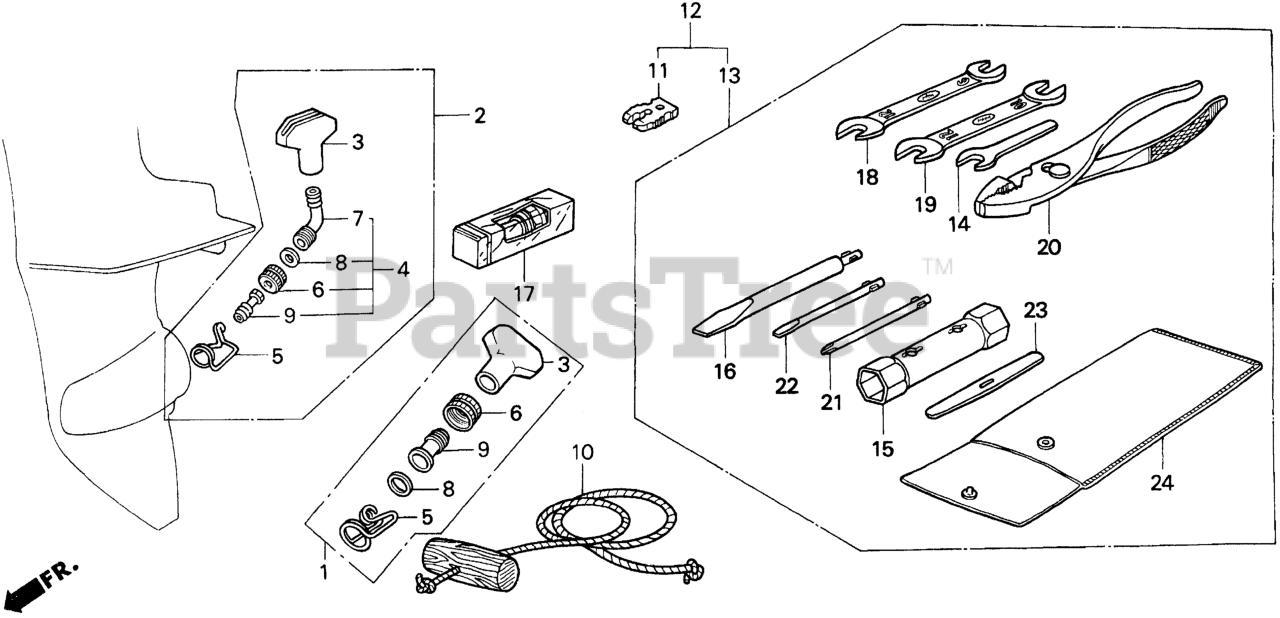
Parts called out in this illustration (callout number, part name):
2	WATER MOUTH KIT Use from Frame SN 1000929 to 1001221.
3	MOUTH, WATER Use from Frame SN 1000929.
5	CLIP, WATER MOUTH Use from Frame SN 1000929.
6	NUT, WATER MOUTH Use from Frame SN 1000929.
7	JOINT, WATER MOUTH Use from Frame SN 1000929 to 1001221.
8	SEAT, WATER MOUTH Use from Frame SN 1000929.
9	JOINT, HOSE Use from Frame SN 1000929.
10	ROPE, STARTER (#5X55") Use from Engine SN 1453515.
13	TOOL KIT (N/A: SEE COMPONENTS)
14	WRENCH (8MM) (OPEN END) (NOT AVAILABLE)
15	WRENCH, BOX (P18X19) (NOT AVAILABLE)
16	SCREWDRIVER, CHECK BOLT
17	SPARK PLUG (DR5HS) (NGK)
18	WRENCH (9X12) (OPEN END)
19	WRENCH (10X12) (OPEN END)
20	PLIERS (135) (KOWA)
21	SCREWDRIVER 1, PHILLIPS (NO.2)
22	SCREWDRIVER 3, STRAIGHT SLOT (NO. 2)
23	LEVER, TIRE
24	BAG, TOOL
